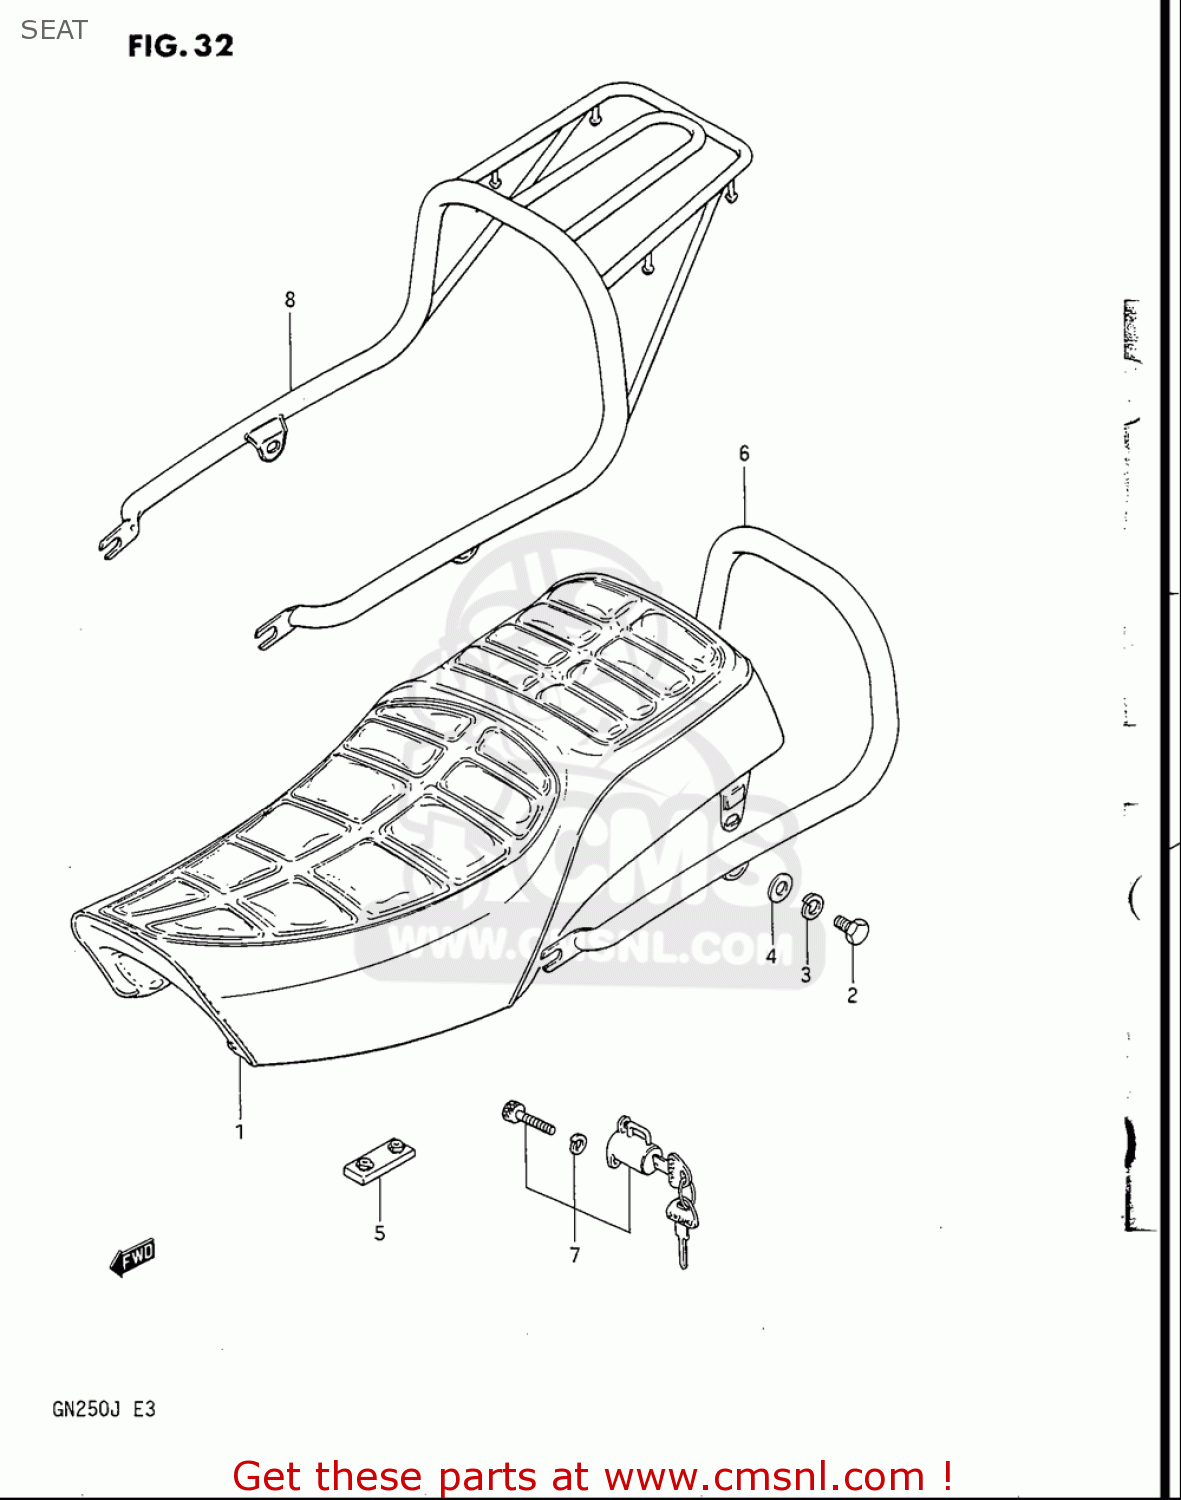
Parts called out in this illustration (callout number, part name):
1	SEAT ASSY
2	BOLT
3	WASHER,LOCK
4	WASHER
5	CUSHION
6	HANDLE,PILLION RIDER
7	LOCK SET,HELMET
